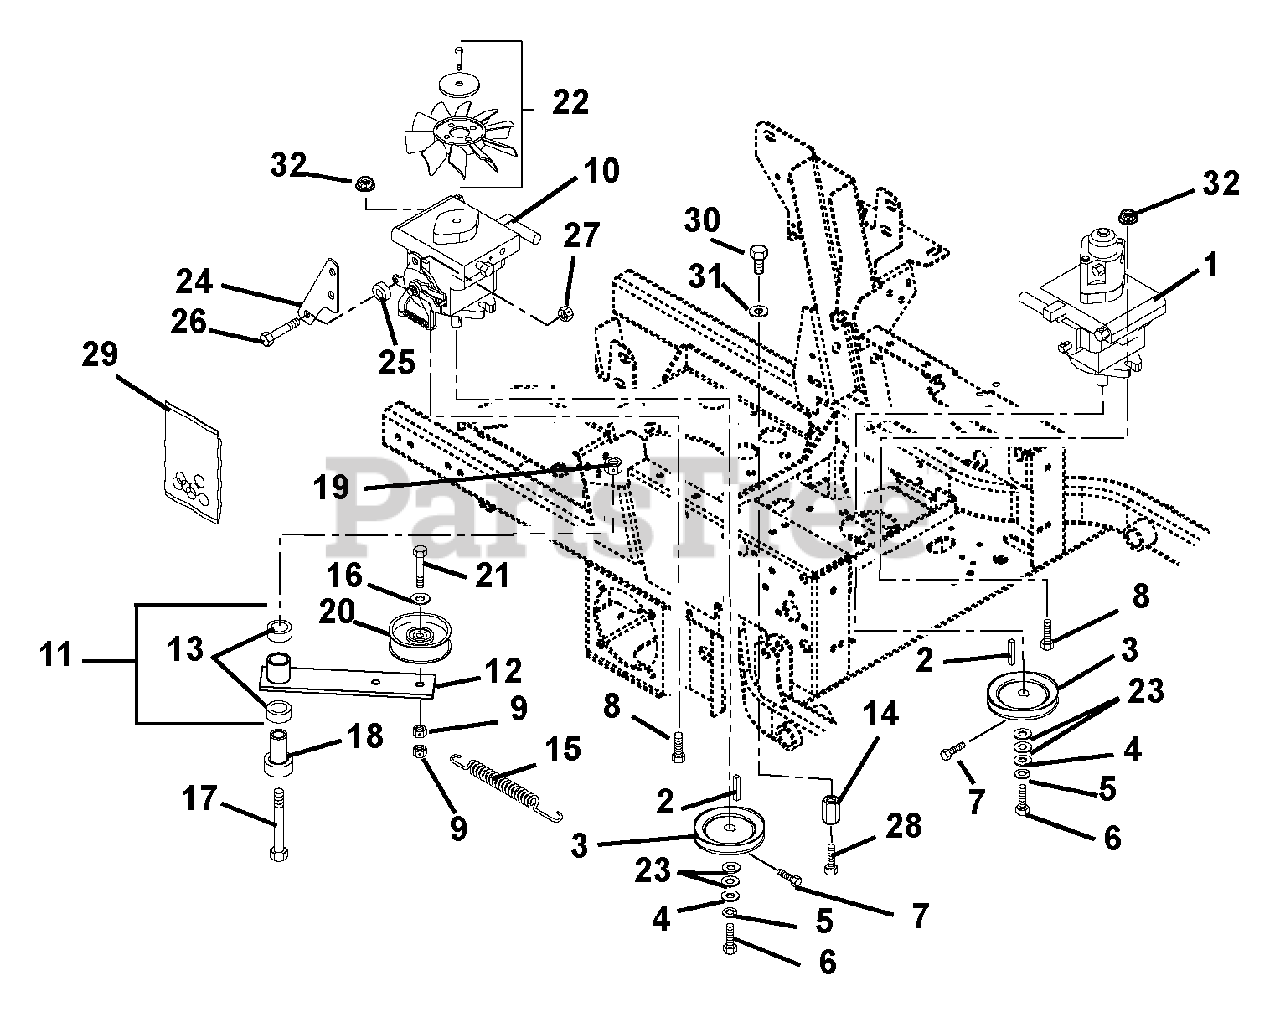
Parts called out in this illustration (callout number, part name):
1	PUMP,10CC DISP,W/AUX,W/REV RTN
2	KEY-STR 5MMX25MMX5MM
3	SHEAVE, PUMP .592 X 4.345
4	WSHR-FL-STL .281X1.000X.063
5	@WSHR-LK .25X.062 REG YWZC
6	BLT-HEX M6 X 1.0X12 YWZC
7	@BLT-HEX .25-20X.50 GR5 YWZC
8	@BLT-RDHDSQNK .44-14X1.50 G5YZ
9	@NUT-LK-TOP-FLG .38-16 YWZC
10	PUMP, BDP-10A-441 (THRU SHAFT)
11	ASSEMBLY,IDLER ARM GRD.DRIVE
12	WMT, IDLER ARM GROUND DRIVE
13	BRG, 1.00 X 1.12 X .75
14	NUT COUPLING .375-16X1.75
15	SPRING, EXTENSION
16	WSHR-FL-STL .390X.75X.125 YWZC
17	@BLT-HEX .50-13X3.50 GR5 YWZC
18	BEARING, PEDESTAL
19	@NUT-LK-TOP-FLG .50-13 YWZC
20	IDLER, FLAT 4.00X1.06
21	@BLT-HEX .38-16X2.25 GR5 YWZC
22	FAN, COOLING
23	@WSHR-FL-STL.656X1.31X.095 YWZ
24	BRACKET, RTN/DAMPER
25	SPACER .344X1.000X.375
26	@BLT-HEX .31-18X1.25 GR5 YWZC
27	@NUT-LK-TOP-FLG .31-18 YWZC
28	@BLT-HEX .38-16X1.50 GR5 YWZC
29	KIT, PUMP SEAL
30	@BLT-HEX .38-16X.75 GR5 YWZC
31	@WSHR-LK .38X.094 REG YWZC
32	NUT-LK-NYL-FLG .44-14 YWZC
